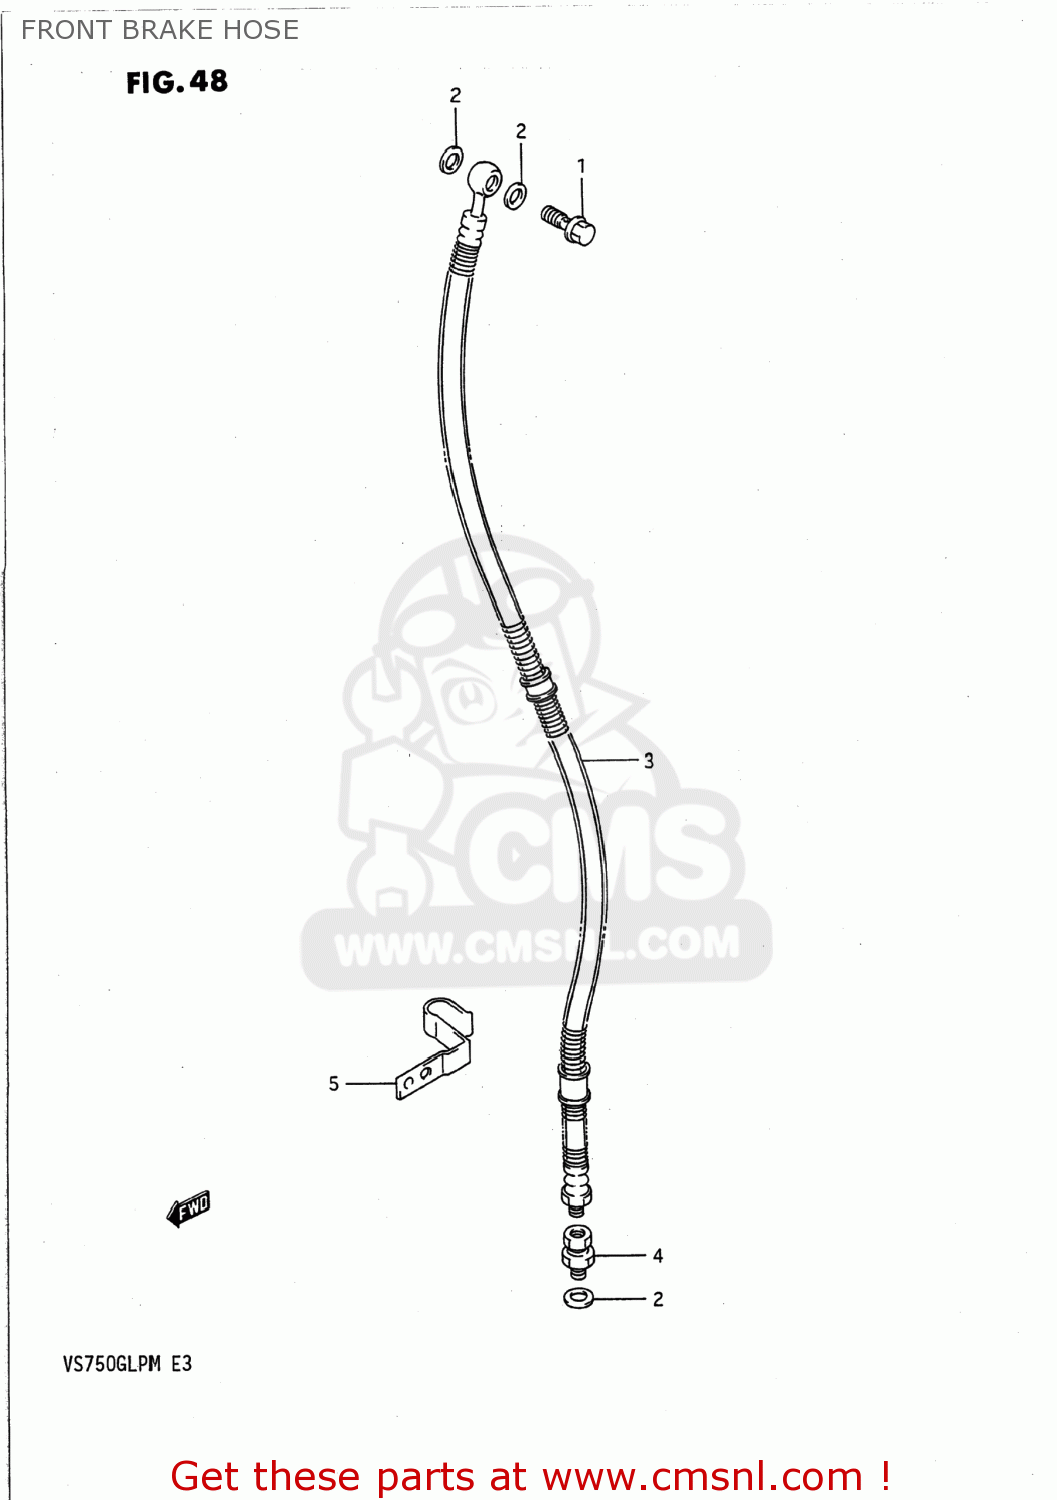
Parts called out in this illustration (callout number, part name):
1	BOLT UNION
2	WASHER(10X15X1.5)
3	HOSE,FR BRAKE
4	ADAPTER,BRAKE HOSE
5	CLAMP,FRONT BRAKE HOSE
